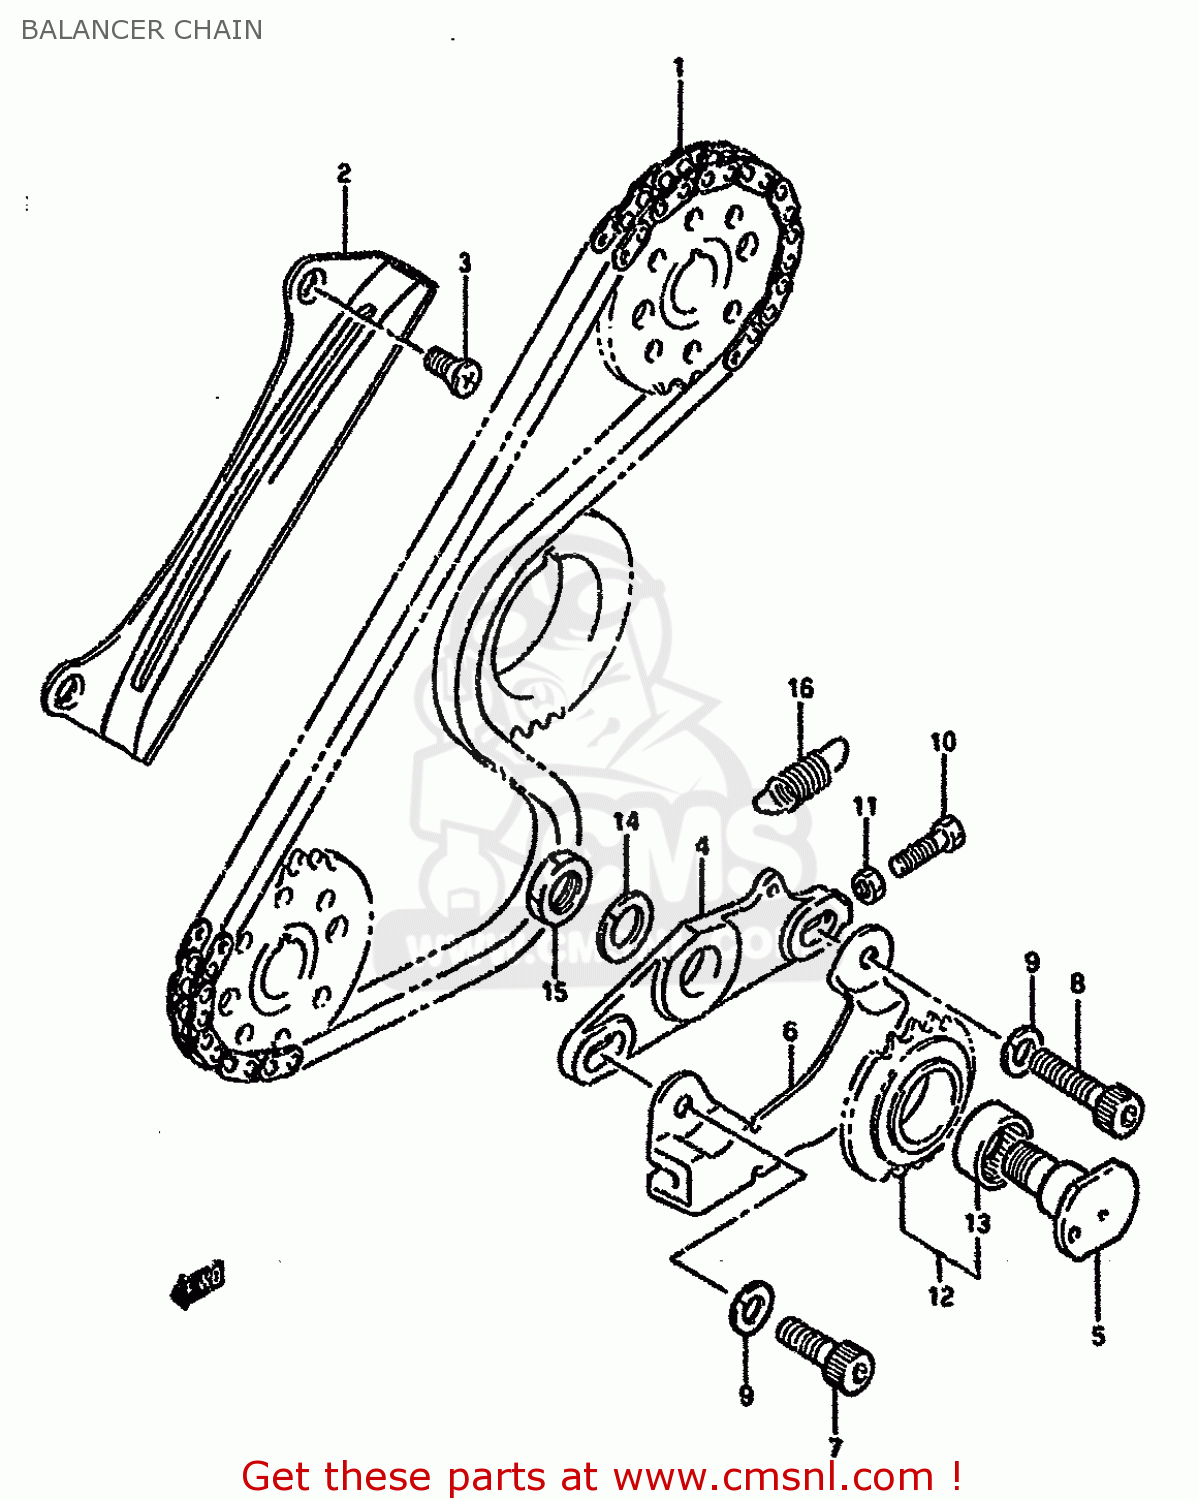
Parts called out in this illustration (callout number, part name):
1	CHAIN,BALANCER
2	GUIDE,BALANCER CHAIN
3	SCREW ,6X16
4	BRACKET,BALANCER CHAIN
5	SHAFT,BALANCER CHAIN TENSIONER
6	GUIDE,BALANCER CHAIN TNSN
7	BOLT(8X22)
8	BOLT
9	WASHER,LOCK
10	BOLT
11	NUT
12	SPRKT,BALANCER CHAIN TENSIONER
13	BEARING(17X23X12)
14	WASHER,LOCK
15	NUT
16	SPRING
